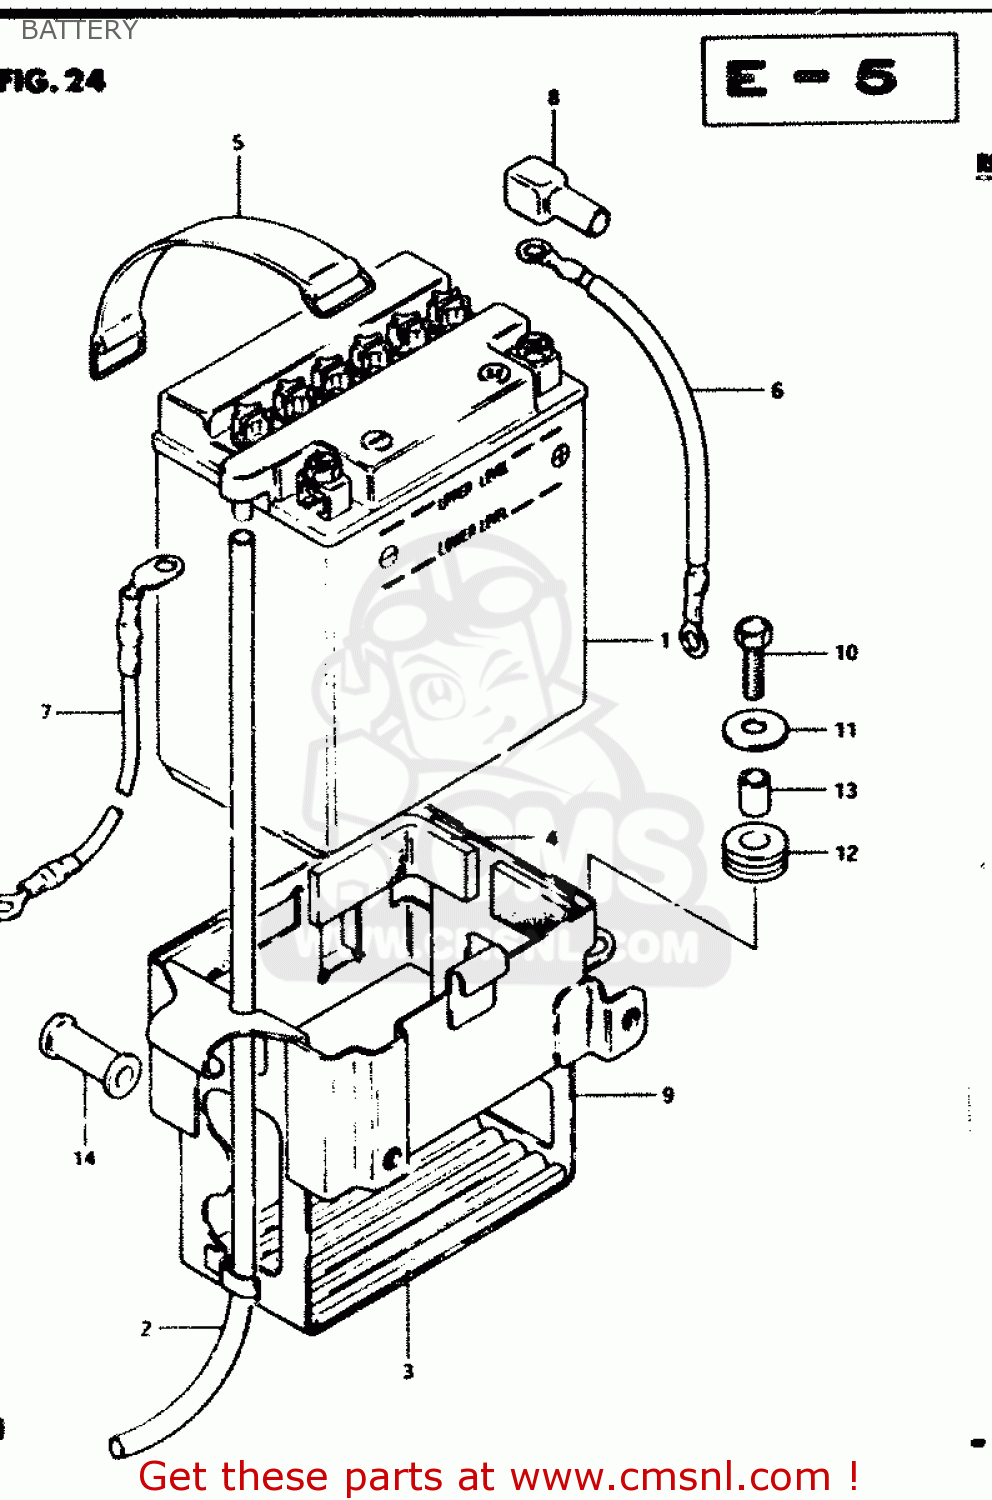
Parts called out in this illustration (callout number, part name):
1	BATTERY ASSY (12V)
2	HOSE,BATTERY EXHAUST
3	PROTECTOR,BATTERY
4	PROTECTOR(20X90)X4
5	BAND
6	WIRE,BATTERY PLUS
7	LEAD WIRE,BATTERY(-)
8	CAP,TERMINAL
9	HOLDER,BATTERY
10	BOLT, UPPER
11	WASHER(6,5X22X1.6)
12	CUSHION
13	SPACER(6.2X8.3X5.7)
14	CUSHION
